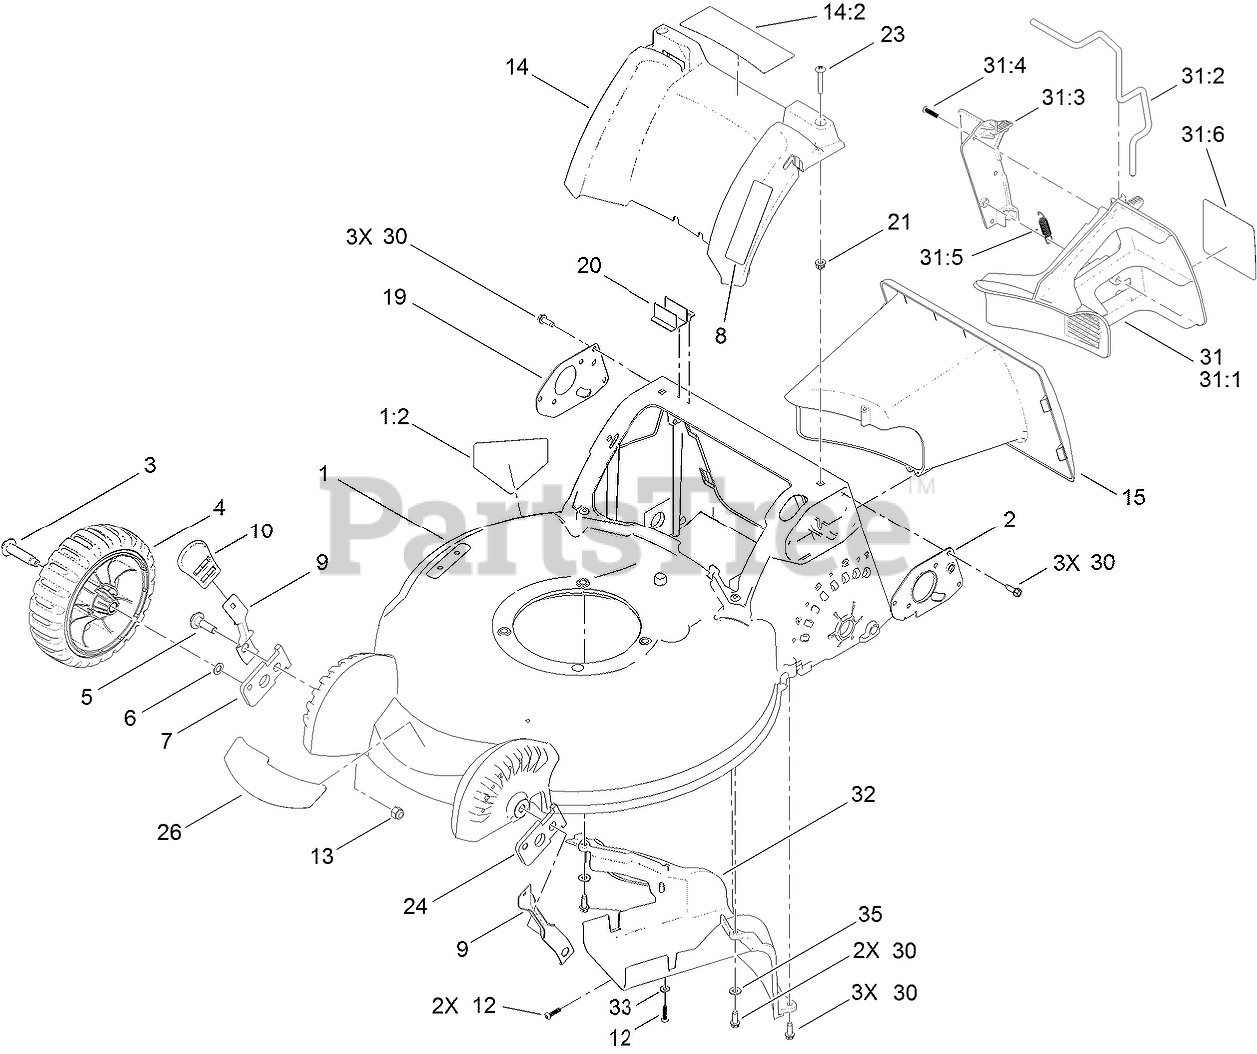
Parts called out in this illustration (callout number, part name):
1	HOUSING ASM
1:2	DECAL-DANGER
2	MOUNT-HANDLE, LH
3	BOLT-SHOULDER
4	8 INCH WHEEL ASM
5	BOLT-SHOULDER
6	WASHER
7	ARM-PIVOT, RH
8	DECAL-QUICK STOW
9	ARM-SPRING, FRONT
10	KNOB-HOC
12	SCREW-PLASTITE
13	NUT-LOCK, NI
14	REAR COVER ASM
14:2	DECAL-WARNING
15	TUNNEL
19	MOUNT-HANDLE, RH
20	MODULE-SWITCH
21	NUT-CLIP
23	SCREW-PTH
24	ARM-PIVOT, LH
26	DECAL-DECK
30	SCREW-HWHTF
31	MULCH PLUG ASM
31:1	PLUG-MULCH, LH
31:2	LATCH-PLUG, MULCH
31:3	PLUG-MULCH, RH
31:4	SCREW-PLASTITE
31:5	SPRING-EXTENSION
31:6	DECAL-PLUG, MULCH
32	BAFFLE-REAR
33	WASHER-FLAT
35	WASHER-FLAT
